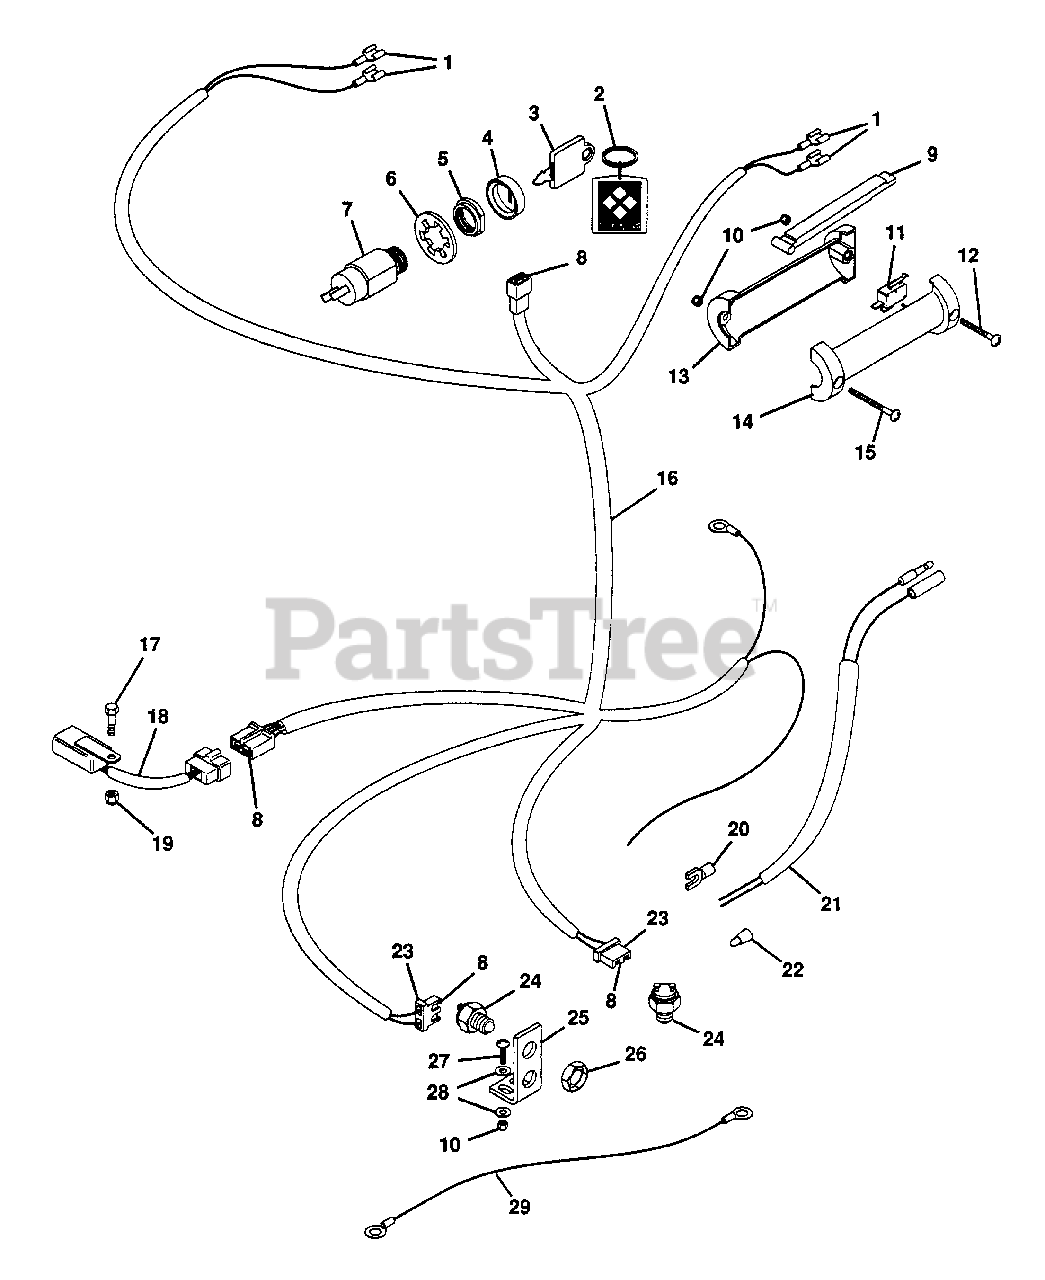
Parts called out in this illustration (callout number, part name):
2	CHAIN, KEY
3	KEY, IGNITION SWITCH
4	BOOT, FOR 9/16 SWITCH
5	NUT, 5/8-32 FOR SWITCH
6	WASHER, LOCK 5/8 INT. TOOTH
7	SWITCH, IGNITION
8	TERMINAL
9	LEVER
10	NUT, LOCK 10-24
11	SWITCH
12	SCREW, MACHINE 10-24X.625 PHD
13	HANDLE, R.H.
14	HANDLE, L.H.
15	SCREW, MACH. 10-24X1.50 PHDCR
16	HARNESS, WIRING
17	BOLT, HEX 1/4-20X.750
18	MODULE, INTERLOCK
19	NUT, LOCK 1/4-20
20	TERMINAL, PRE-INSULATED
23	CONNECTOR, 2-WIRE SWITCH
24	SWITCH, NEUTRAL START
25	BRACKET, INTERLOCK SWITCH
26	NUT, STAMPED 9/16-18
27	SCREW, MACHINE 10-24X.75 PHD
28	WASHER, FLAT .188X.438X.049
29	WIRE, GROUND
